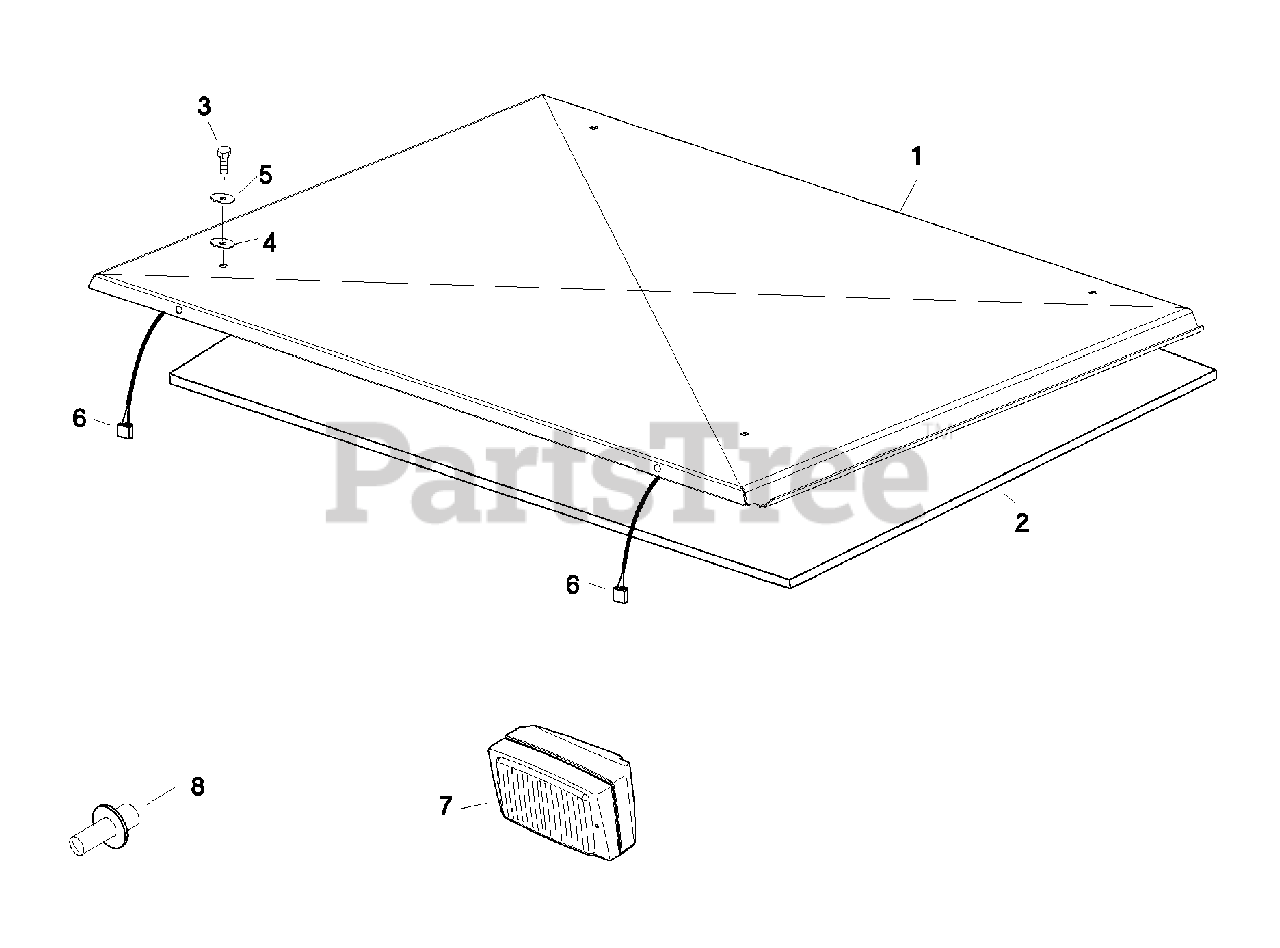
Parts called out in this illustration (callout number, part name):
2	Material lining fareb 201
3	Hexagon head screw M6x16
4	Rubber washer 5x20x2
5	Auto body washer 6x20x1.5
7	Headlamp H3
8	Halogen lamp H3
